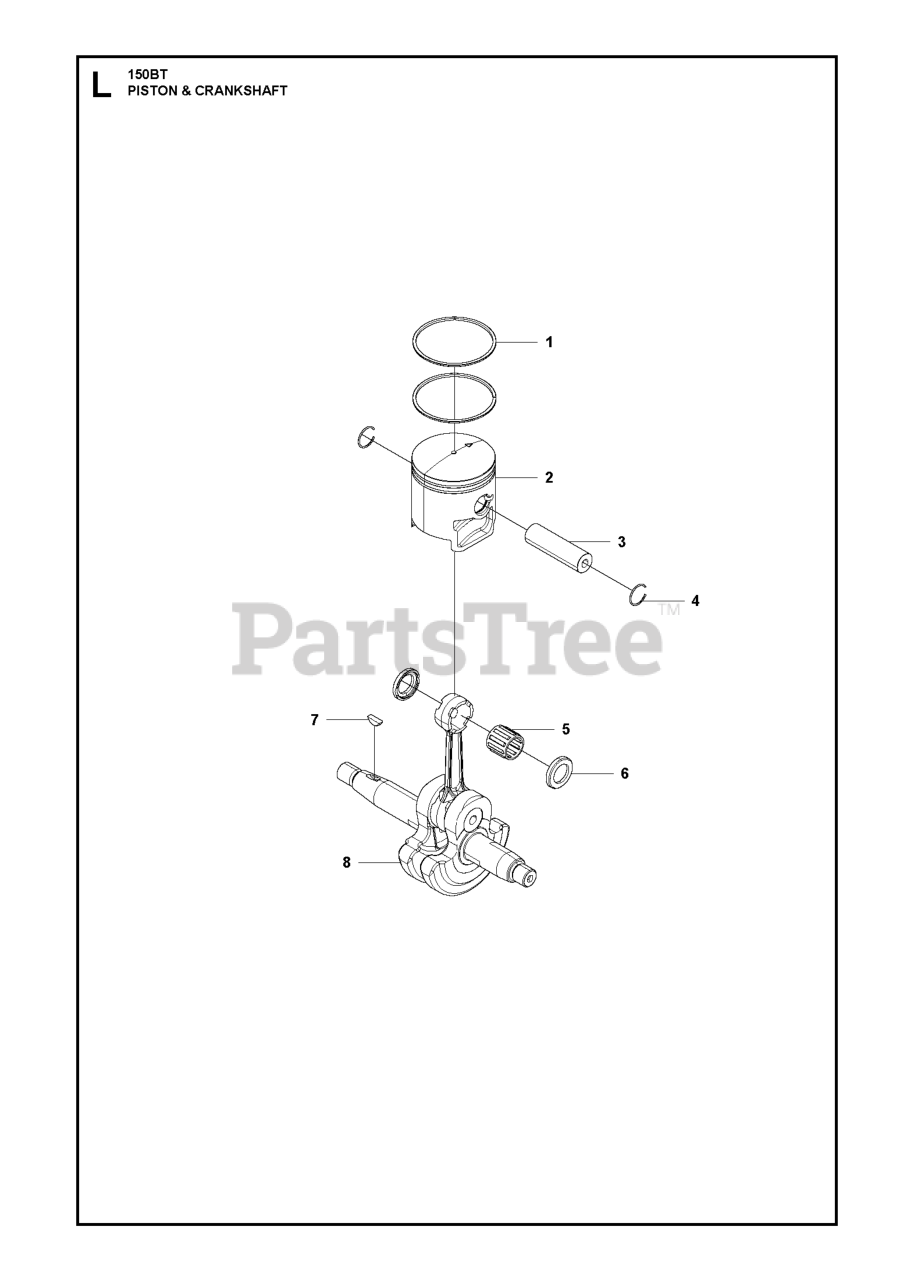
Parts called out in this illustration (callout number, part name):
1	PISTON RING
3	PISTON PIN
8	CRANKSHAFT
